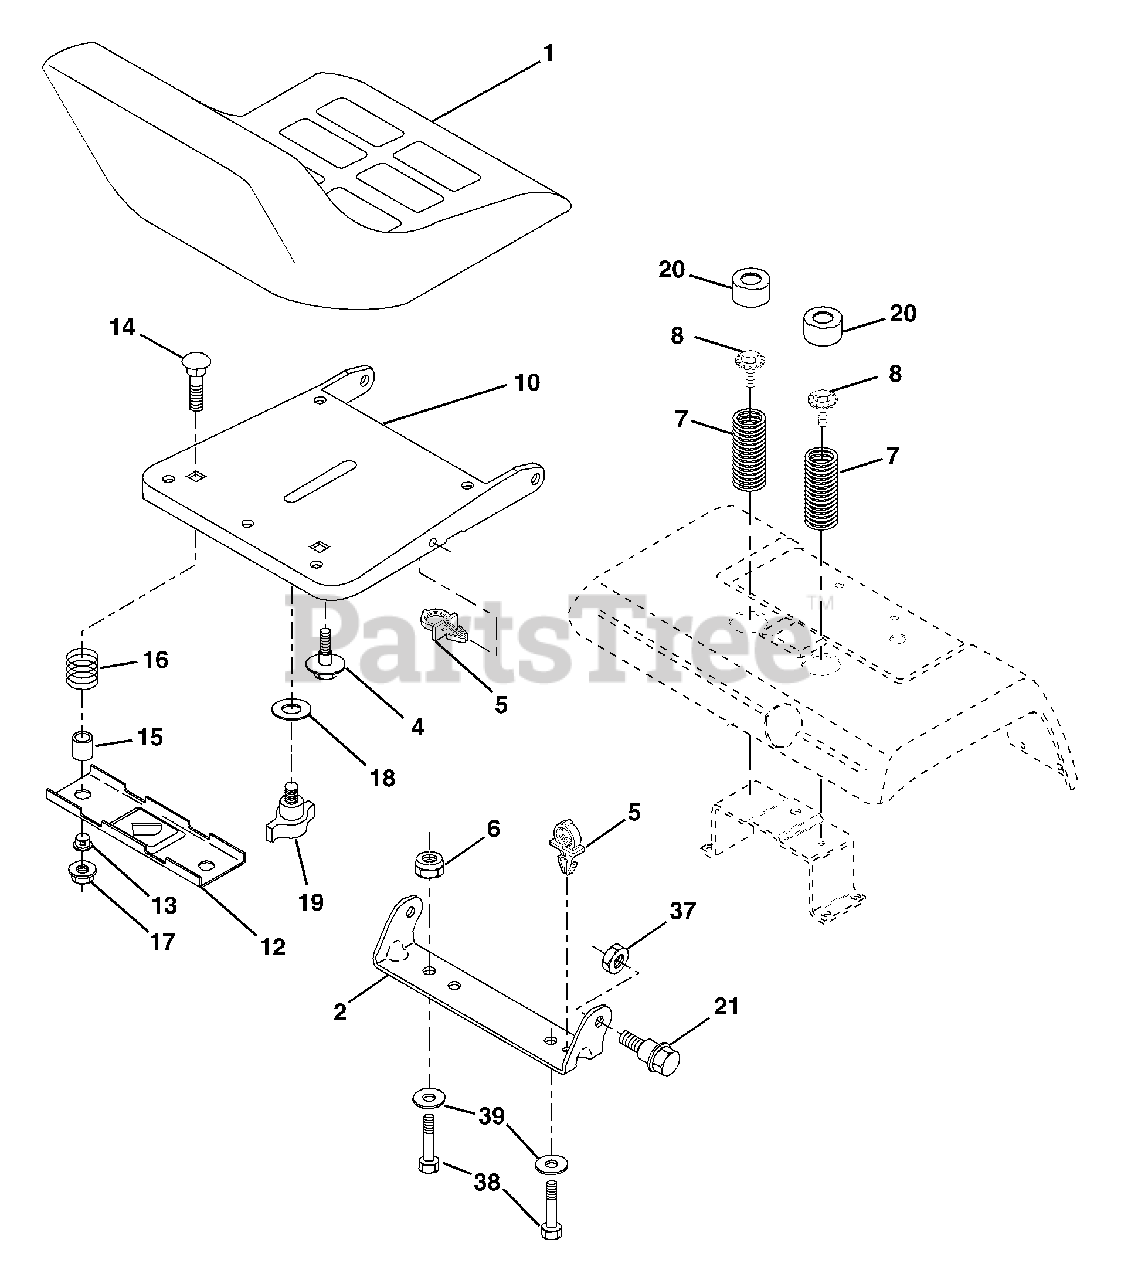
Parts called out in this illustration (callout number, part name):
1	Seat
2	Bracket, Pivot Seat
4	Bolt, Shoulder 5/16-18 x .62
5	Clip, Push-In Hinged
6	Nut, Crownlock 3/8-16
7	Spring, Seat Cprsn.
8	Bolt 5/16-18 UNC x 3/4 w/Sems
10	Pan, Seat
12	Bracket, Mounting Switch
13	Bushing, Snap
14	Bolt, Carriage 1/4-20 x 1-1/2
15	Spacer, Split
16	Spring, Cprsn.
17	Nut, Lock 1/4 Lg. Flg. Gr. 5
18	Washer 17/32 x 1-3/16 x 12 Ga.
19	Knob, Seat
20	Cap, Spring Seat Blk
21	Bolt 5/16-18 Unc-2A
22	Nut, Crownlock 5/16-18
38	Washer Flat 13/32 x 1 x 10 Ga.
39	Bolt 3/8-16 x 1
